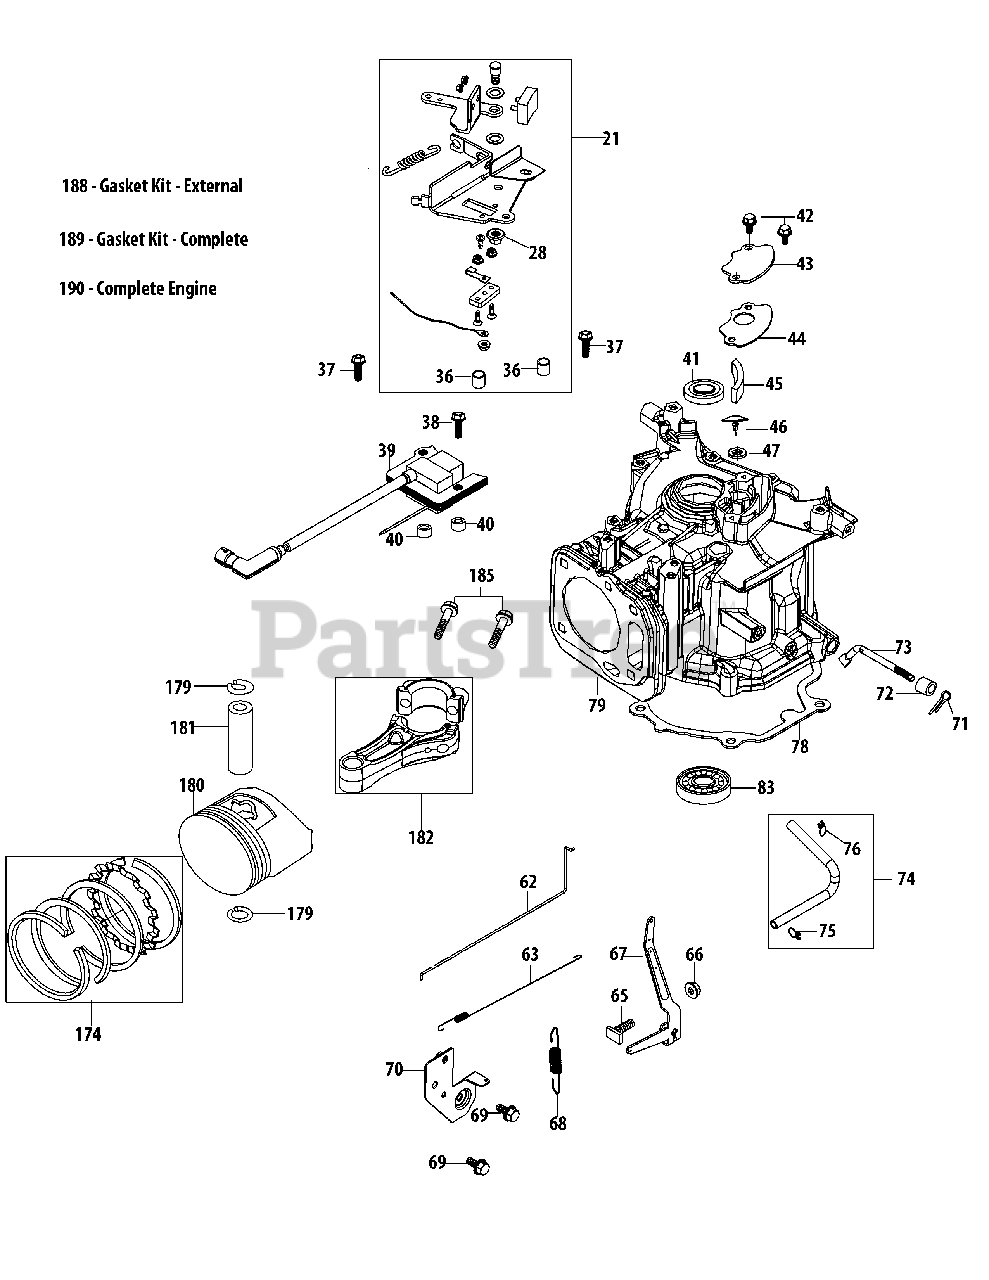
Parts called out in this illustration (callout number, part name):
21	Brake Assembly
28	Brake Arm Nut
36	Brake Spacer
37	Bolt M6X35
38	Bolt M6X30
39	Ignition Coil Assembly
40	Ignition Coil Spacer
41	Upper Crankshaft Seal
43	Breather Cover Plate
44	Breather Gasket
45	Breather Screen
46	Breather Valve
47	Breather Valve Base
62	Throttle Linkage
63	Throttle Linkage Spring
65	Governor Arm Bolt
66	Governor Arm Nut M6
67	Governor Arm
68	Governor Spring
69	Bolt M6X12
70	Component Bracket
71	Governor Arm Shaft Cotter Pin
72	Governor Seal
73	Governor Arm Shaft
74	Breather Hose Assembly
75	Breather Hose Clamp
76	Breather Hose Clamp
77	Breather Hose
78	Crankcase Cover Gasket
79	Short Block Assembly
83	Main Bearing
174	Piston Ring Set
179	Piston Pin Snap Ring
180	Piston
181	Piston Pin
182	Connecting Rod Assembly
185	Connecting Rod Bolt
188	Gasket Kit - External
189	Gasket Kit - Complete
190	Complete Engine
